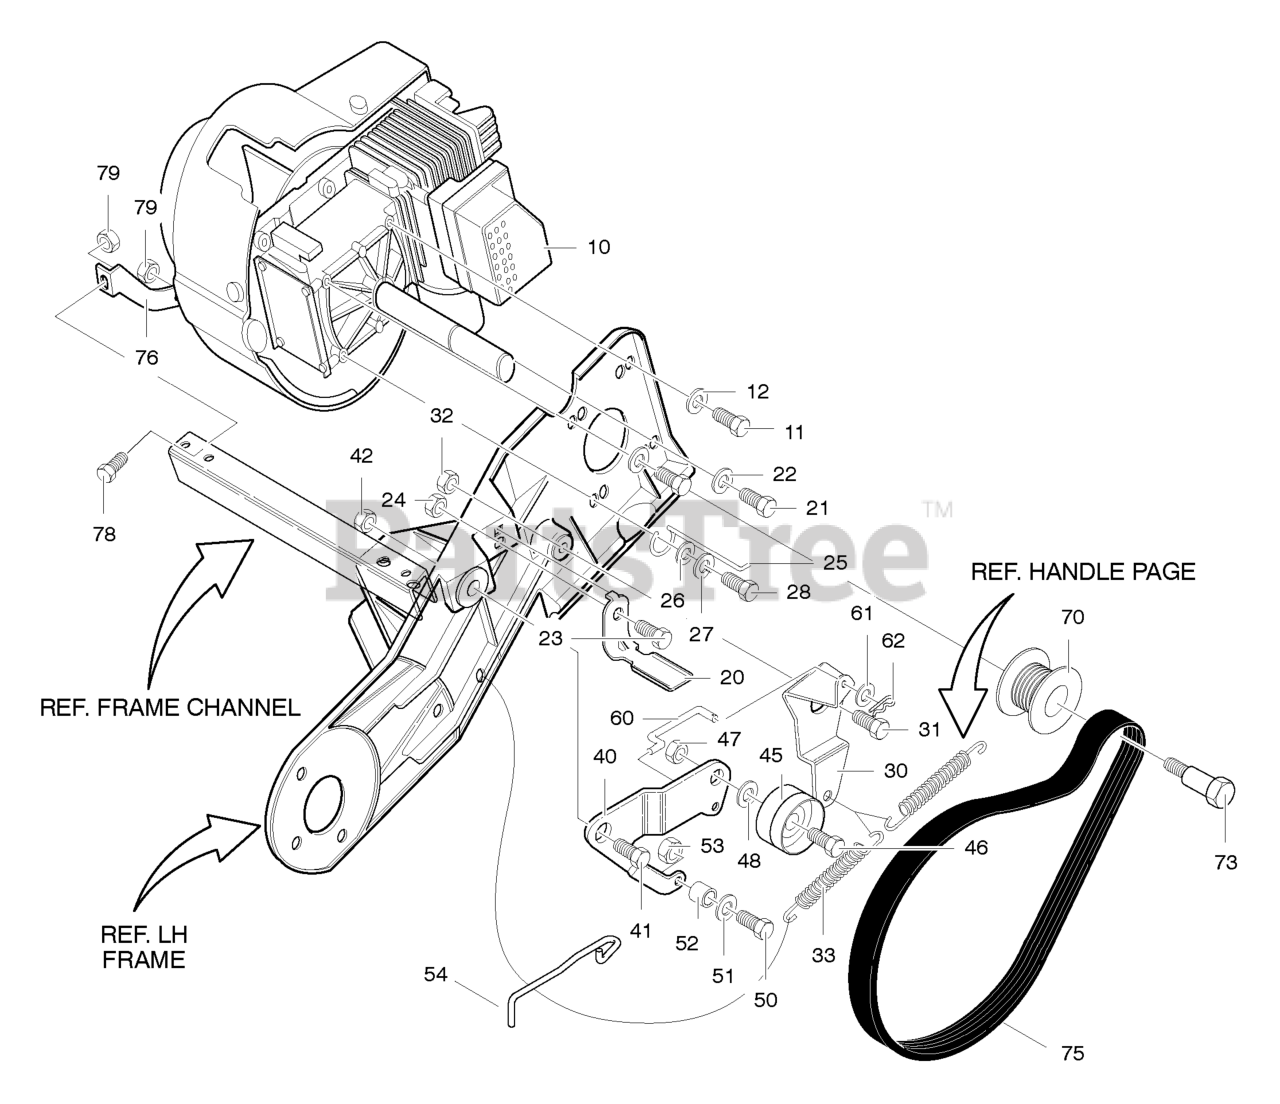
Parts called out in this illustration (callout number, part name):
10	ENGINE
12	WASHER
20	LF PAD, BRAKE
21	SCREW
22	WASHER
23	SCREW,1/4-20X.63
24	NUT, 1/4-20
25	GUIDE, BELT
26	WASHER, FLAT
27	WASHER
30	ARM, IDLER
32	NUT, 5/16-18
33	SPRING, EXTENSION
40	LF ARM, IDLER
42	NUT, 5/16-18
45	PULLEY, IDLER
47	NUT
48	WASHER, FLAT
50	SCREW, 1/4-20X2.00
51	WASHER, FLAT
52	ROLLER, PINCH
53	NUT, 1/4-20
54	WIRE, BRAKE
60	ROD, CLUTCH
61	WASHER, FLAT
62	PIN, COTTER
73	BOLT, SHOULDER
76	BRACKET, SUPPORT
78	SCREW
79	NUT, 5/16-18
